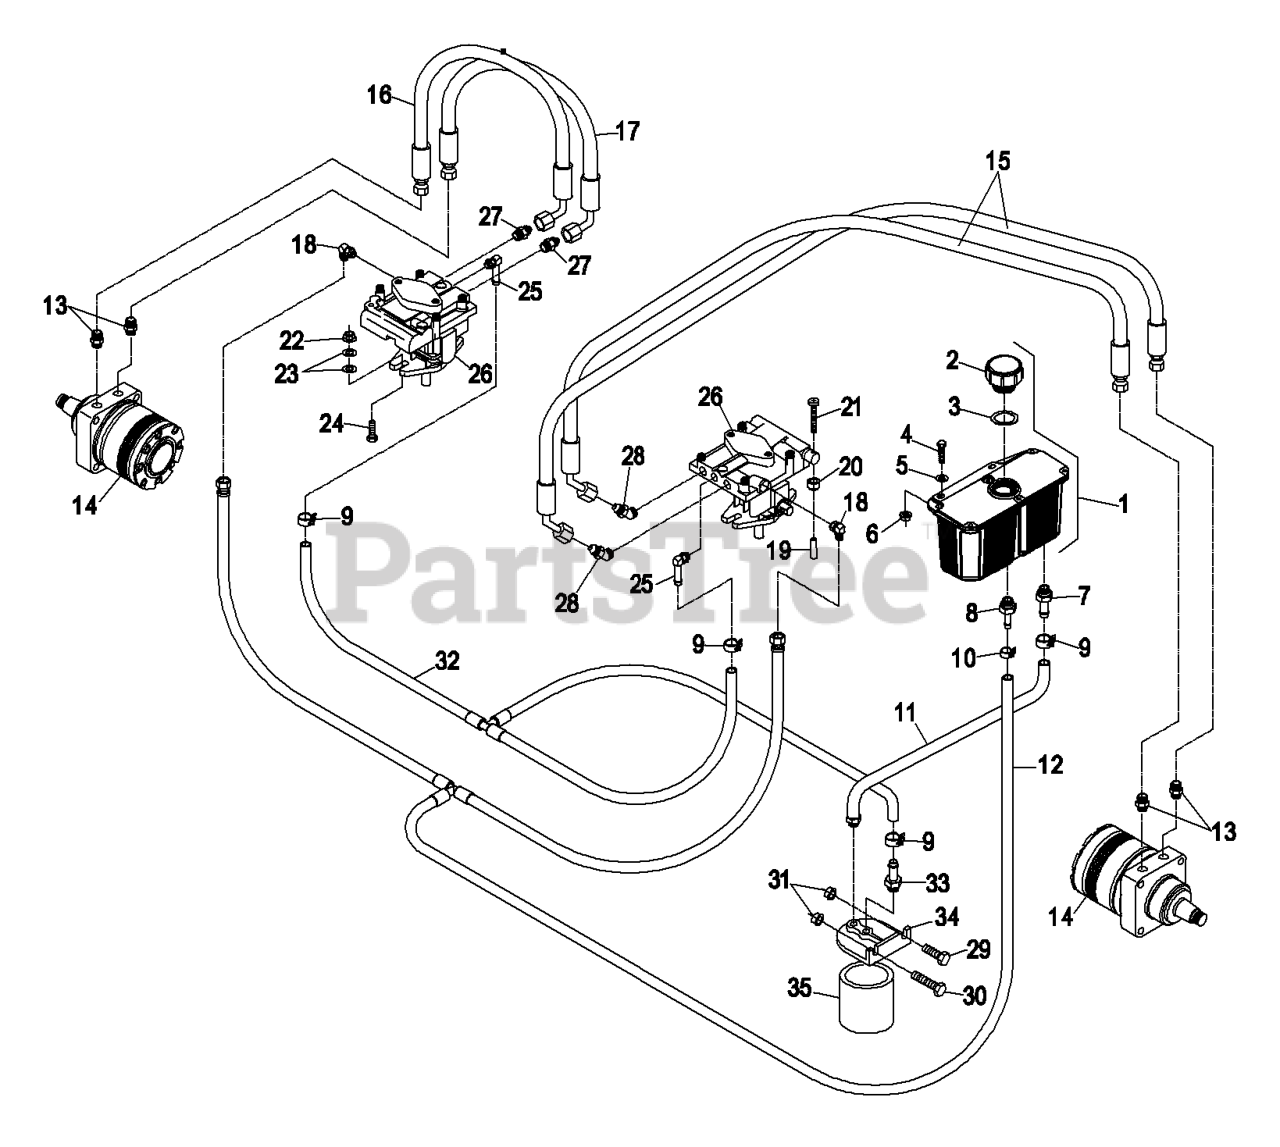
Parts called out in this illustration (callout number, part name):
1	HYD RESERVOIR ASM
2	Cap-Reservoir, HYD
3	GASKET-CAP
4	SCREW-HH
5	WASHER-FLAT
7	ADAPTER-STRAIGHT
8	ADAPTER-STRAIGHT
9	CLAMP-HOSE
10	CLAMP-HOSE
13	FITTING-STRAIGHT
14	HYD MOTOR ASM
15	HOSE,HIGH PRESSURE
17	HOSE-PRESSURE, HIGH
18	FITTING-90 DEG
19	GRIP-VALVE, DUMP
20	NUT-LOCK, NI
22	NUT-HHF, WHIZ
23	WASHER-FLAT
24	SCREW-HH
25	FITTING
27	FITTING-STRAIGHT
28	FITTING-HYD, 45 DEG
29	SCREW-HH
30	SCREW-HH
33	FITTING-STR
